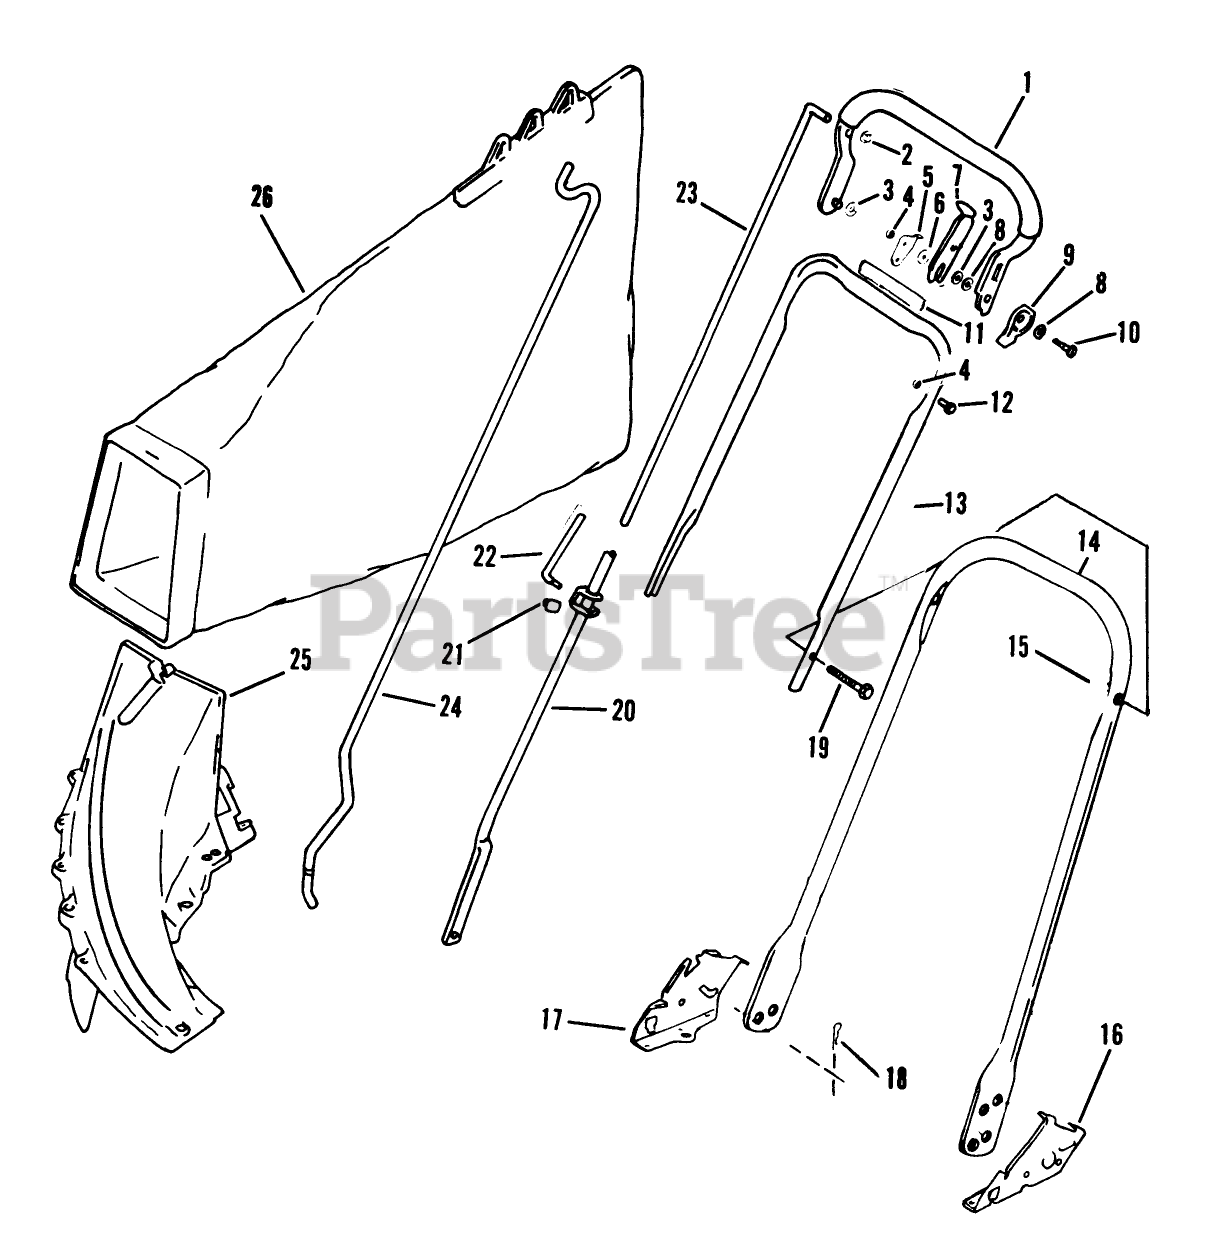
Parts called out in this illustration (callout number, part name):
3	WASHER M
4	LOCKNUT E
5	HANDLE STOP
6	WASHER
10	BOLT PIONEER
12	SCREW-HANDLE STOP
13	Handle-Center
15	LOCKNUT E
18	HAIR PIN
26	89802 LB WHOLE GOODS
